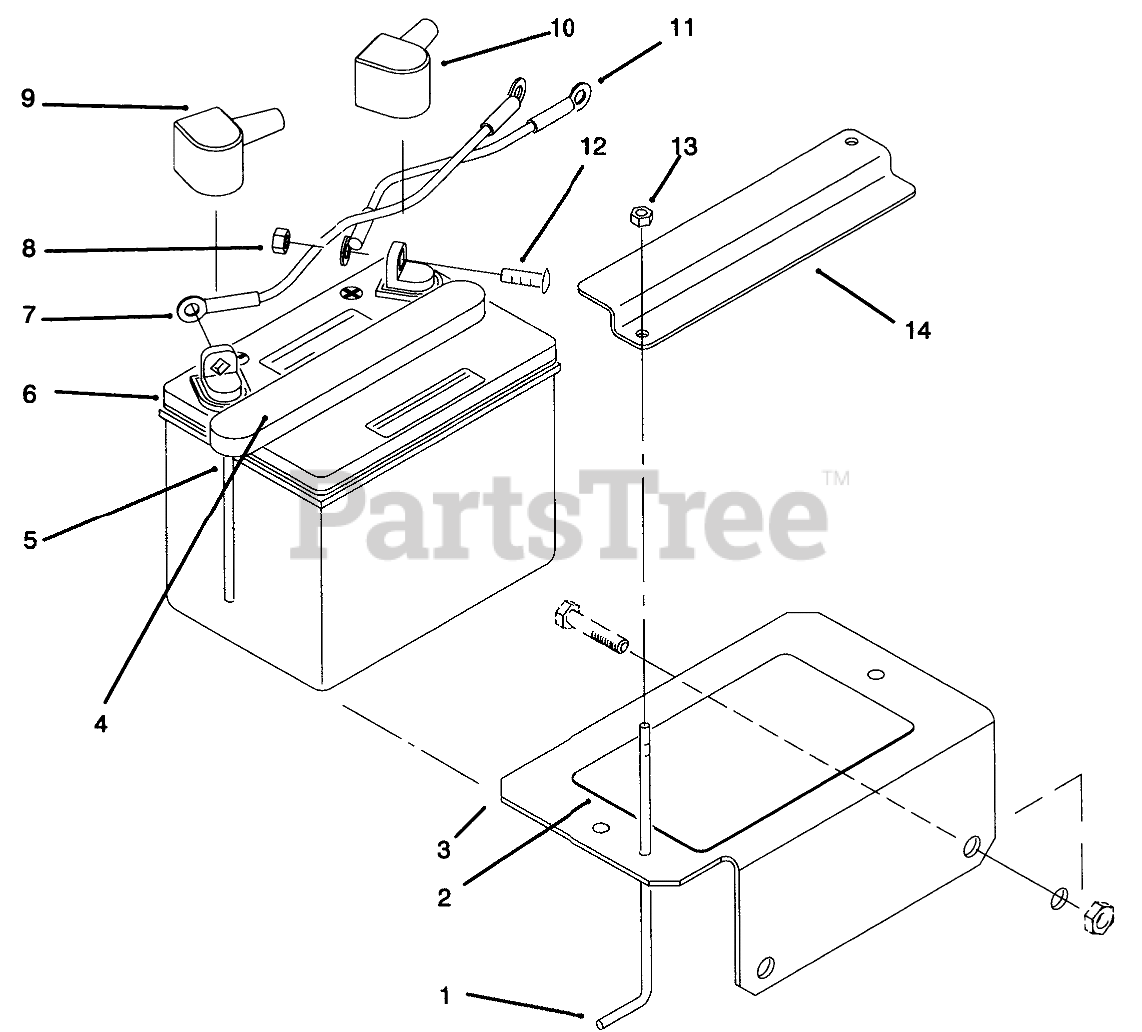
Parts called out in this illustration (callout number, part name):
1	ROD-SUPPORT, BATTERY
2	PAD-SKID, ANTI
3	Holder-Battery
5	TUBE-VENT
6	Battery
7	WIRE ASM
8	NUT-KEPS
9	BOOT-TERMINAL, BLACK
10	BOOT-TERMINAL, RED
11	WIRE-SOLENOID/STARTER
12	SCREW-HH
13	NUT-LOCK, NI
14	Clamp-Battery
